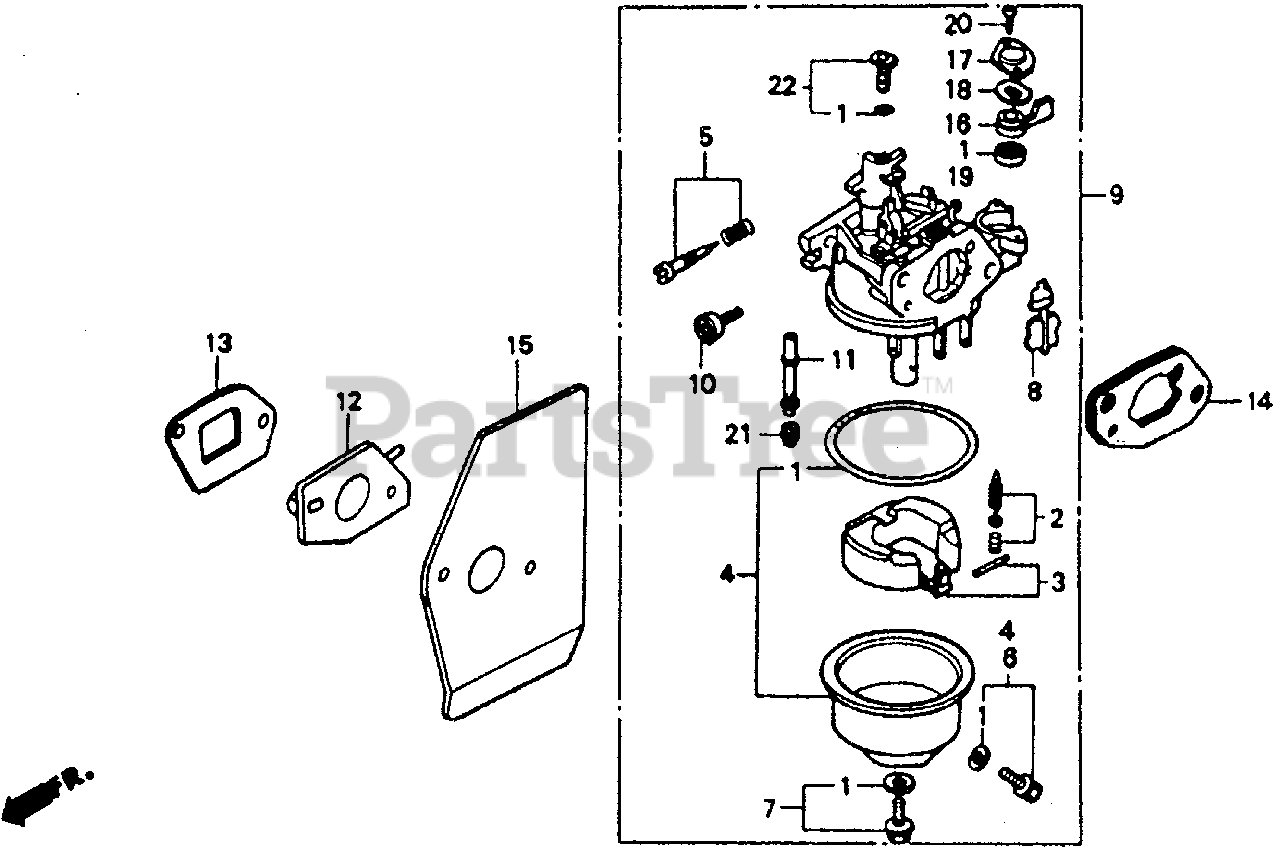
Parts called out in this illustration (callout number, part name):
1	GASKET SET
1	GASKET SET (CARBURETOR NO.)
2	VALVE SET, FLOAT (CARBURETOR NO.) (SEAT NOT INCLUDED)
3	FLOAT SET
4	CHAMBER SET, FLOAT (CARBURETOR NO.)
5	SCREW SET, PILOT (Honda Code 1441500). (CARBURETOR NO.)
6	SCREW SET, DRAIN (Honda Code 1672187). (CARBURETOR NO.)
7	SCREW SET
8	CHOKE SET (CARBURETOR NO.)
9	CARBURETOR ASSY. (BE40A B)
9	CARBURETOR ASSY. (BE40A E)
9	CARBURETOR ASSY. (BE40A G/H)
10	SCREW, THROTTLE STOP
11	NOZZLE, MAIN
11	NOZZLE, MAIN (CARBURETOR NO.)
12	INSULATOR, CARBURETOR
13	GASKET, INSULATOR
14	SPACER, CARBURETOR
15	GASKET, CARBURETOR
16	LEVER, VALVE
17	PLATE, LEVER SETTING (CARBURETOR NO.)
18	SPRING, PETCOCK LEVER (CARBURETOR NO.)
19	GASKET, VALVE
20	SCREW, PAN (3X8)
20	SCREW, PAN (3X8) (CARBURETOR NO.)
21	JET, MAIN (#62) (Honda Code 0635482). (CARBURETOR NO.)
21	JET, MAIN (#65) Use up to Engine SN BB30A D.
21	JET, MAIN (#68) Use up to Engine SN BB30A D.
21	JET, MAIN (#70) Use up to Engine SN BB30A D.
22	JET SET, PILOT (#35)
22	JET SET, PILOT (#38)
